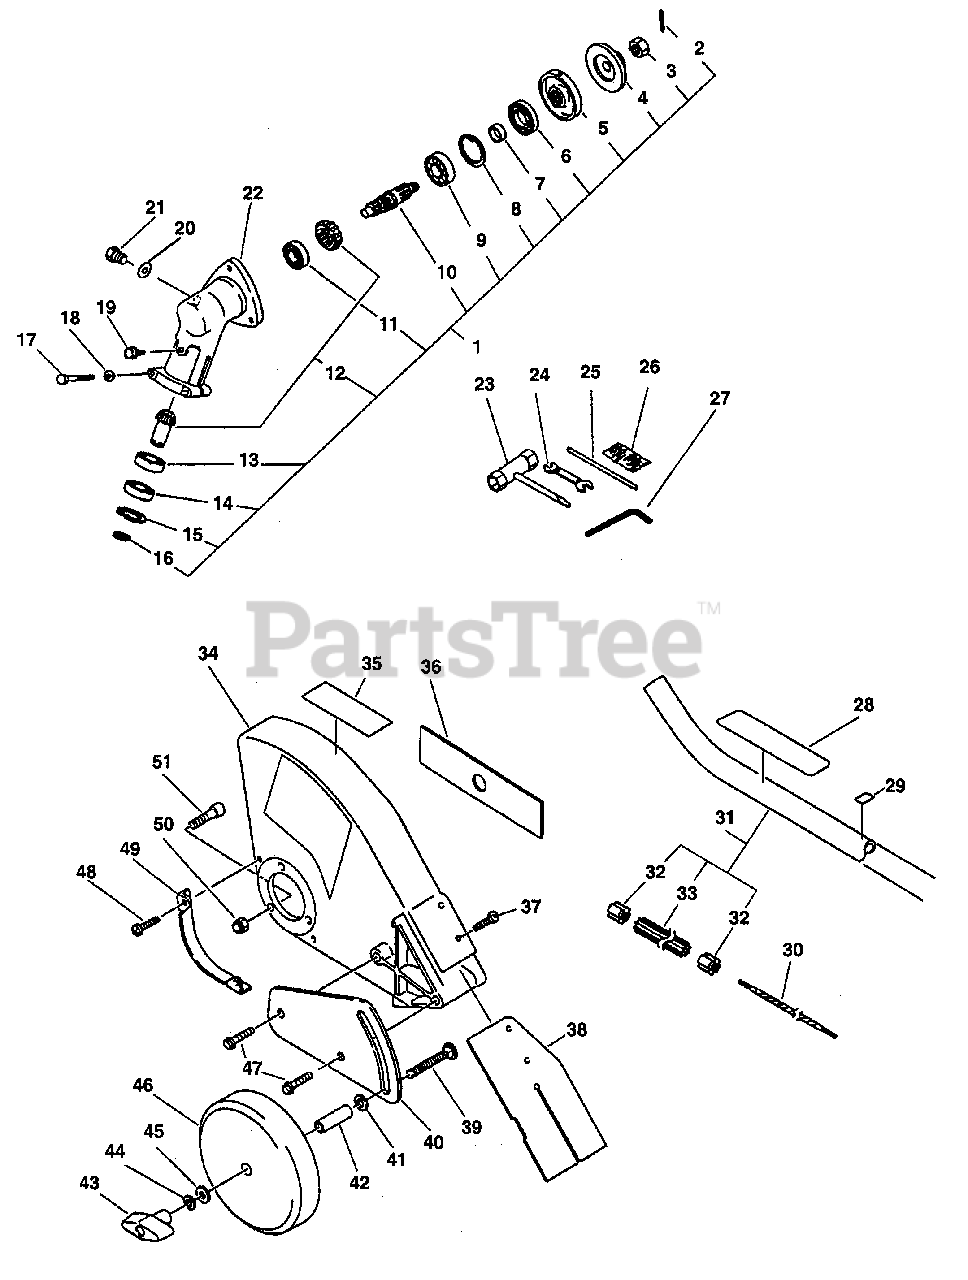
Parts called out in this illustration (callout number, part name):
1	Housing asy, gear
2	Pin, split 2x22
3	Nut 10 (l-h)
4	Plate, adapter (l)
5	Plate, adapter (u)
6	Seal, oil 17
8	Retaining ring 20
9	Bearing, ball 6201
10	Shaft, p.t.o.
11	Bearing, ball 626
12	Gear set
13	Bearing, ball 609
14	Bearing, ball 609
15	Retaining ring
16	Retaining ring 18
17	Bolt 5x30
18	Washer 5
19	Screw 5x12
20	Washer, circular
22	Case, gear
23	Wrench, w/screwdriver
24	Spanner 8x10
25	Locking tool
26	Pin 2x22 (w/pouch)
27	L-wrench (3mm)
28	Label, caution
29	Label, location
30	Shaft, flexible (lower)
31	Housing asy, drive shaft (lower-pe)
33	Liner, flexible (lower)
34	Shield, blade
35	Label, caution
36	2-cutter blade
37	Screw 4x20
38	Flap, debris
40	Bracket, wheel
41	Washer 10 (10.5x21x2)
42	Collar 12
43	Nut, wing
44	Washer, spring 8
45	Washer 8
46	Wheel 6x1.5
48	Screw 4x16
49	Plate, protection
50	Locknut 5
51	Bolt, h.s. 5x22
